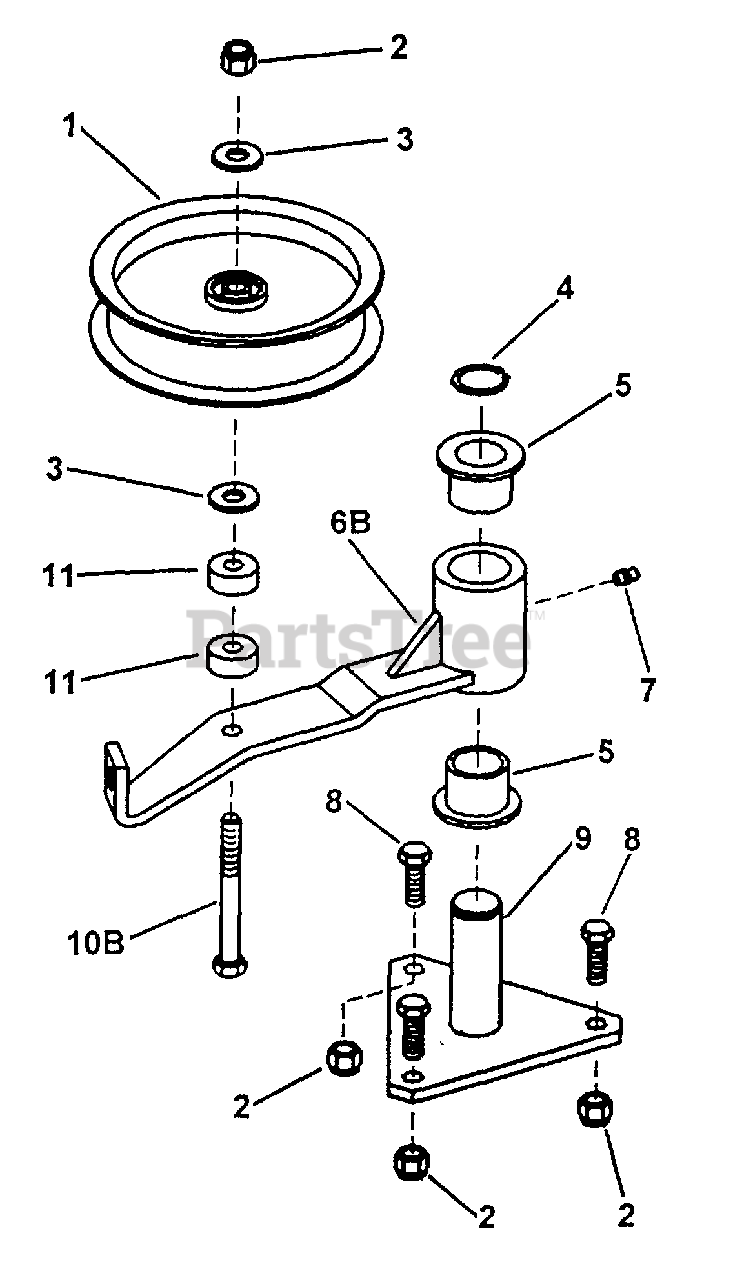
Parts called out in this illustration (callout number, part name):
1	PULLEY, Idler (5.00 O.D.)
2	NUT, 3/8-16 HEX NYLON LOCK
3	WASHER, 3/8" USS
4	RING, 1" Retaining
5	BUSHING
6B	IDLER ARM (36")
7	FITTING, Lube
8	BOLT, 3/8-16 X 1" GD5 CZ
9	PIVOT, Idler Arm
10B	BOLT, 3/8-16 x 3-1/4" Hex Head Cap, Grade 5 (36")
11	BUSHING, .38" I.D. x 1" O.D. x .410"
